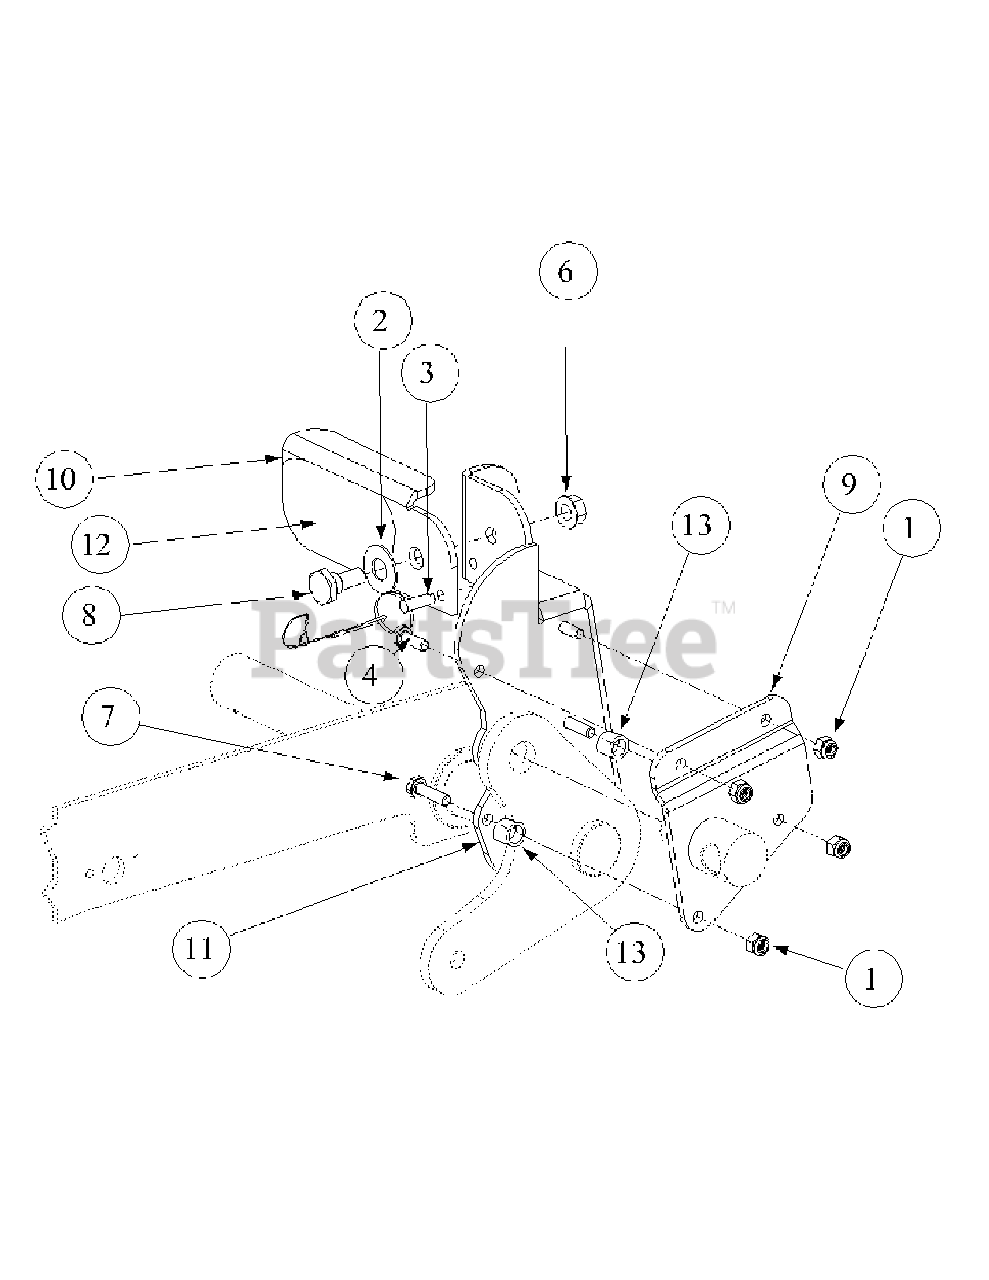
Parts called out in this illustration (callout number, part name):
1	Lock Nut, Nylon Insert, 1/4-20
2	Washer, 1/2 x 1 Shim
3	Detent Pin, w/12" Lanyard
4	Hex Cap Screw, 1/4-20, .75
6	Hex Nut, Flange Lock 3/8-16
7	Hex Cap Screw, 1/4-20, 1.00
8	Shoulder Screw, .50x.27 Lg., 3/8-16
9	Foot Lift Backup Pedal
10	Deck Foot Pedal Lift
11	Deck Foot Pedal Lift Holder
12	Deck Foot Lift Pad
13	Turnbuckle Sleeve
